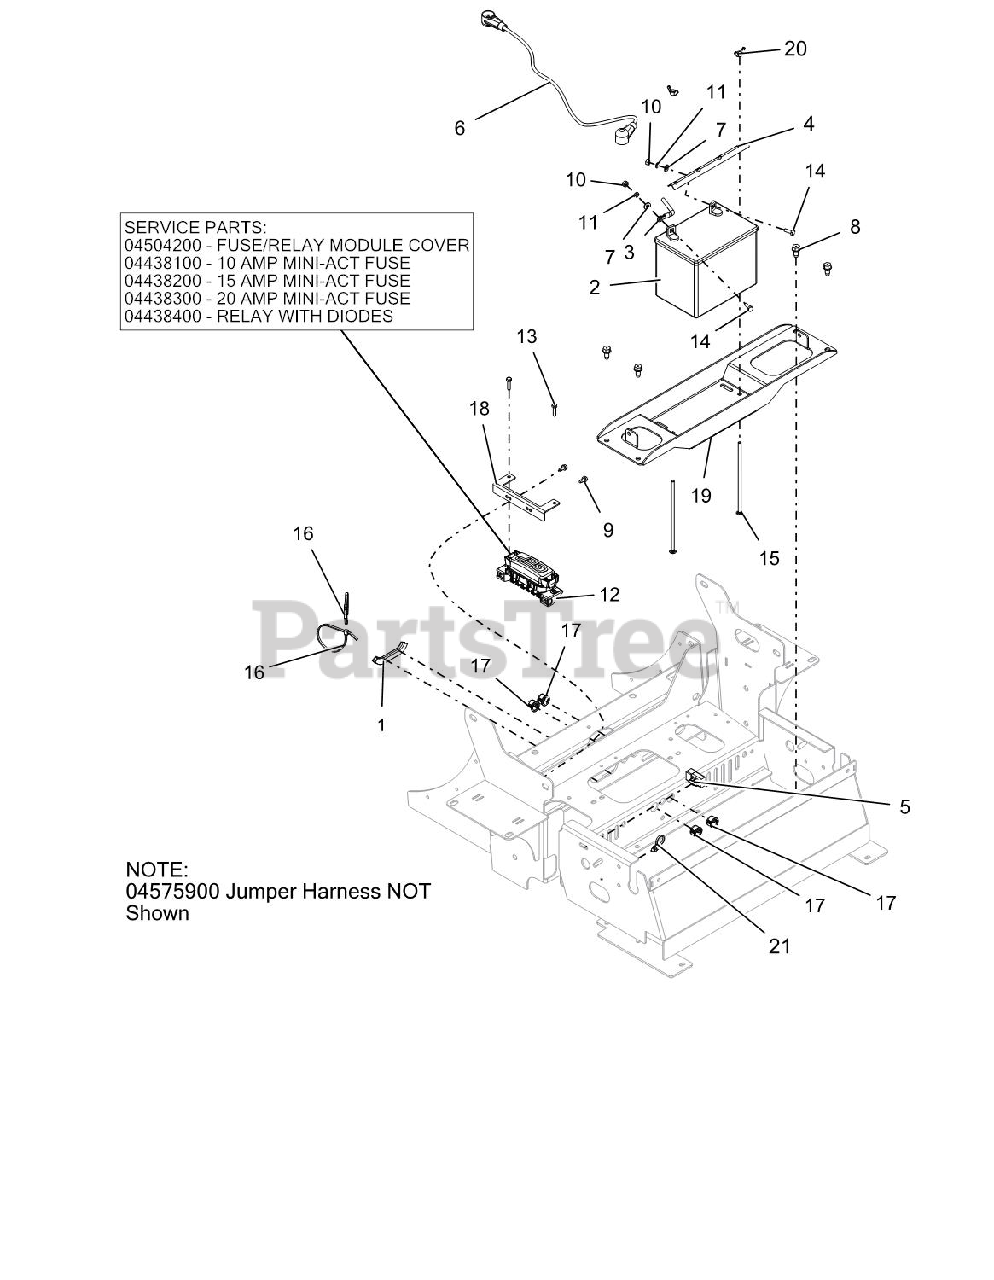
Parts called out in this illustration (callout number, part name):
1	STRIP, COWL - 1.50 LG
2	BATTERY, 300 CCA 10U1L
3	CABLE, NEGATIVE BATTERY 35.00"
4	HOLD DOWN - BLK
5	SWITCH, SNAP IN -N.O./N.O
6	CABLE, POS BATT W/ BOOTS 6 X 35
7	WSHR-FL-STL.281X.62X.065 YWZC
8	SCR-TAP .38-16X.75 HWH TR YWZ
9	SCR-TAP .25-20X.50 HWH TR YWZ
10	NUT-HEX .25-20 YWZC
11	WSHR-LK .25X.062 REG YWZC
12	HARNESS, PT400 GAS WIRE
12	FUSE/RELAY MODULE COVER
12	10 AMP MINI-ACT FUSE
12	15 AMP MINI-ACT FUSE
12	20 AMP MINI-ACT FUSE
12	RELAY WITH DIODES
13	@BLT-HEX M6-1.0X25 YWZC
14	BLT-HEX .25-20X.75 GR5 YWZC
15	BLT-RDHDSQNK .25-20X7.50 G2 YWZC
16	CABLE, TIE 5.50 LG
17	BUSH, PANEL SNAP .687X.875X.56
18	BRKT, FUSE HOLDER MOUNTING-RED
19	TRAY, BATTERY-RED
20	NUT-LOCKING WING 1/4-20
21	CABLE TIE W/ TREE (.25 HOLE)
